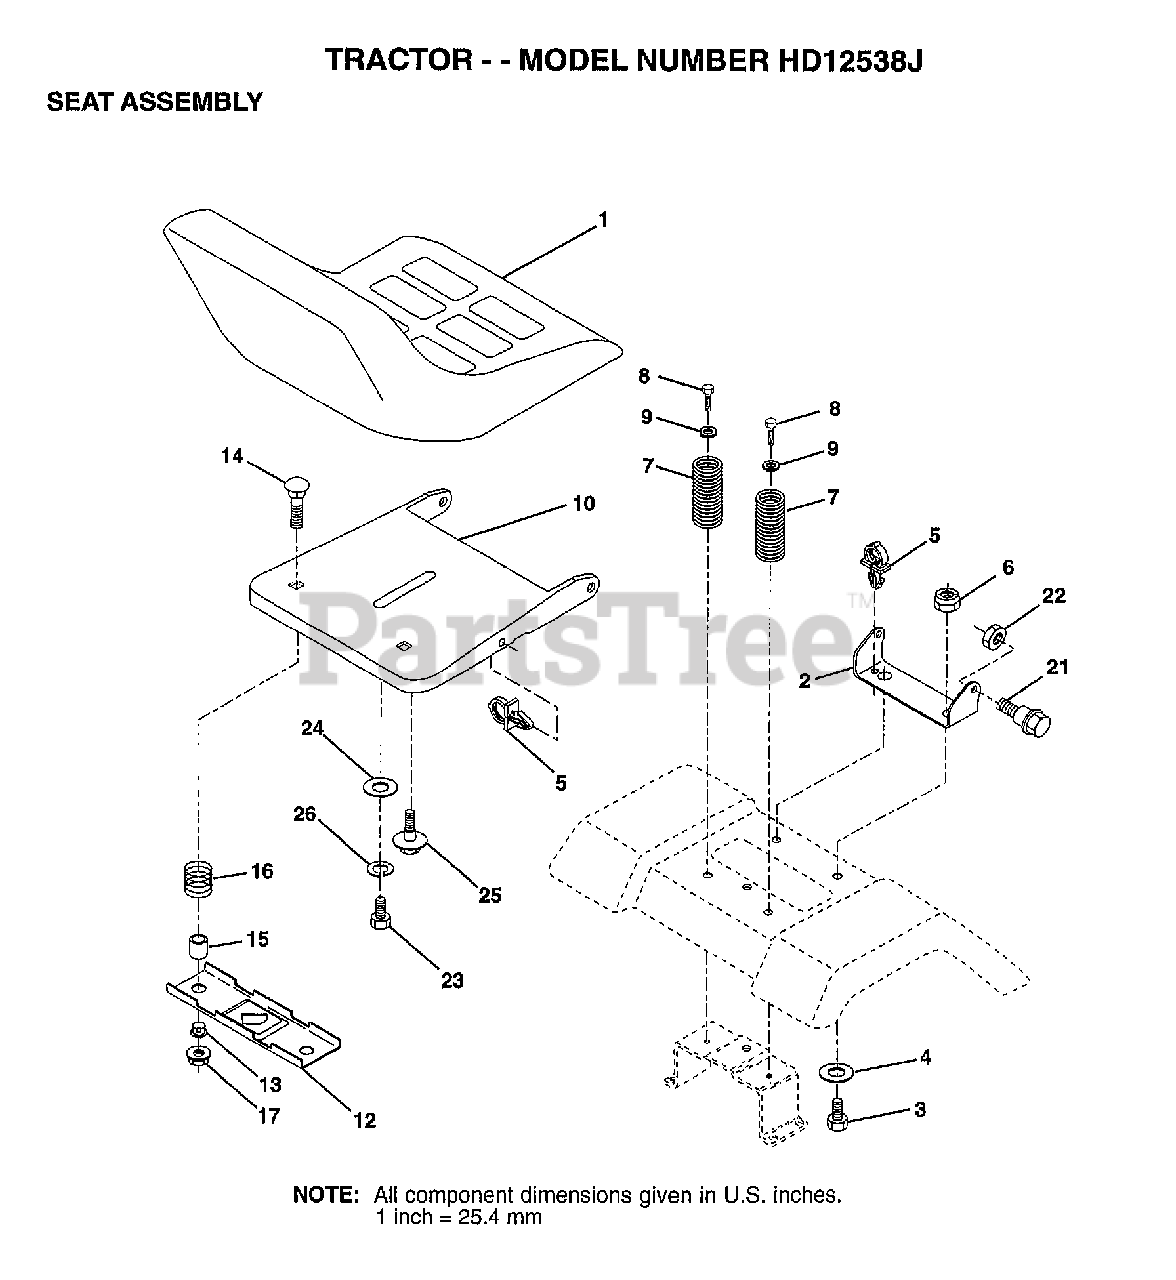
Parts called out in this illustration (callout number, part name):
2	BRACKET PVT SEAT
3	BOLT
4	WASHER PM
5	CLIP.PUSH-IN.HING
6	NUT
7	SPRING COMPRESSIO
8	SCREW GTV
9	WASHER
10	PAN-SEAT
12	BRKT SWITCH
13	BUSHING
14	BOLT-RD HD SQ NK
15	SPLIT SPACER
16	SPRING
21	"BOLT,SHOULDER"
22	NUT
23	BOLT
24	WASHER
25	"BOLT,SHOULDER"
26	LOCKWASHER
